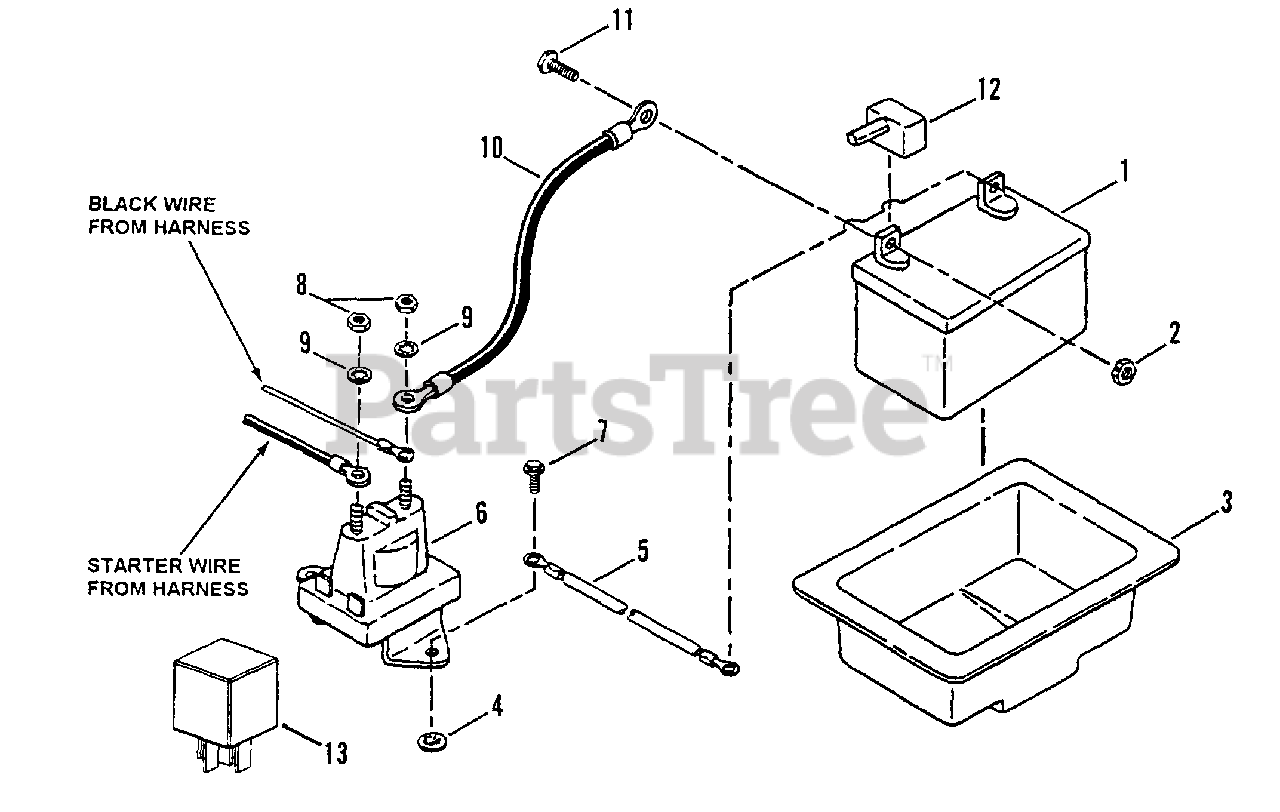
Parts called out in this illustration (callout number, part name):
1	KIT, Battery
2	NUT, 1/4-20 Hex Center Lock Grade B or 5
3	TRAY, Battery
4	RETAINER, Screw
5	CABLE, Ground (Black)
6	SOLENOID
7	SCREW, 1/4-20 x 1/2 Self-Tapping
8	NUT, 1/4-20 Hex Jam
9	WASHER, 1/4 Internal Tooth Lock
10	CABLE, Positive (Red)
11	SCREW, 1/4-20 x 5/8" Hex Head Cap Gr. 5
12	COVER, Positive Terminal
13	RELAY
